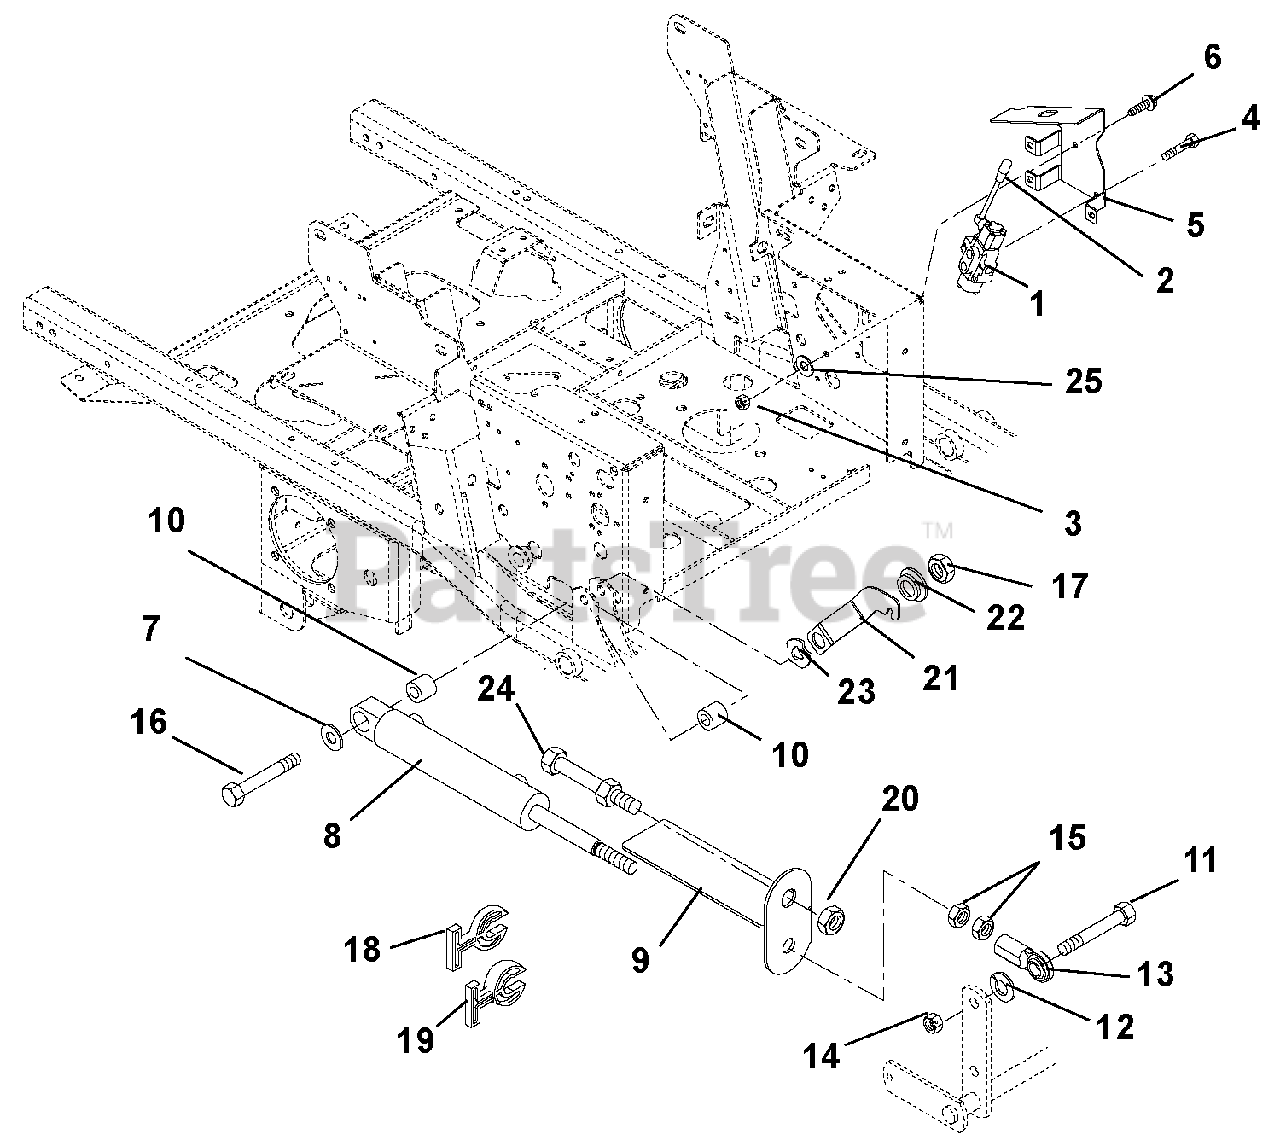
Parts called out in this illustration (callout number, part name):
1	Valve, Hydraulic Lift
2	Knob (Service Only)
3	Nut, Locking Center .31-18
4	Bolt, Hex .31-18 x 2.0 Grade 5
5	Bracket, Valve Mounting
6	Screw, Tapping Hex Washer Head .38-16 x .50
7	Washer, Flat Steel .515 x 1.625 x .25
8	Cylinder, Hydraulic Lift
9	Strap, Cut Indicator / Guard
10	Bushing .516 x 1.00 x 1.05
11	Bolt, Hex .62-11 x 2.25 Grade 8
12	Washer, Lock .62 x .156
13	Rod End, Right Hand Female .625
14	Nut, Locking Center .62-11
15	Nut, Jam .625-18
16	Bolt, Hex .50-13 x 3.75 Grade 5
17	Nut, Locking Top Flange .50-13
18	Stop, Cylinder .34 Thick
19	Stop, Cylinder .68 Thick
20	Nut, Jam .75-16
21	Latch, Footboard
22	Bushing, Flange .515 x .75 x .275 x 1.12
23	Washer, Wave .076 x 1.12 x .08
25	Washer, Locking .31 x .078 Regular
